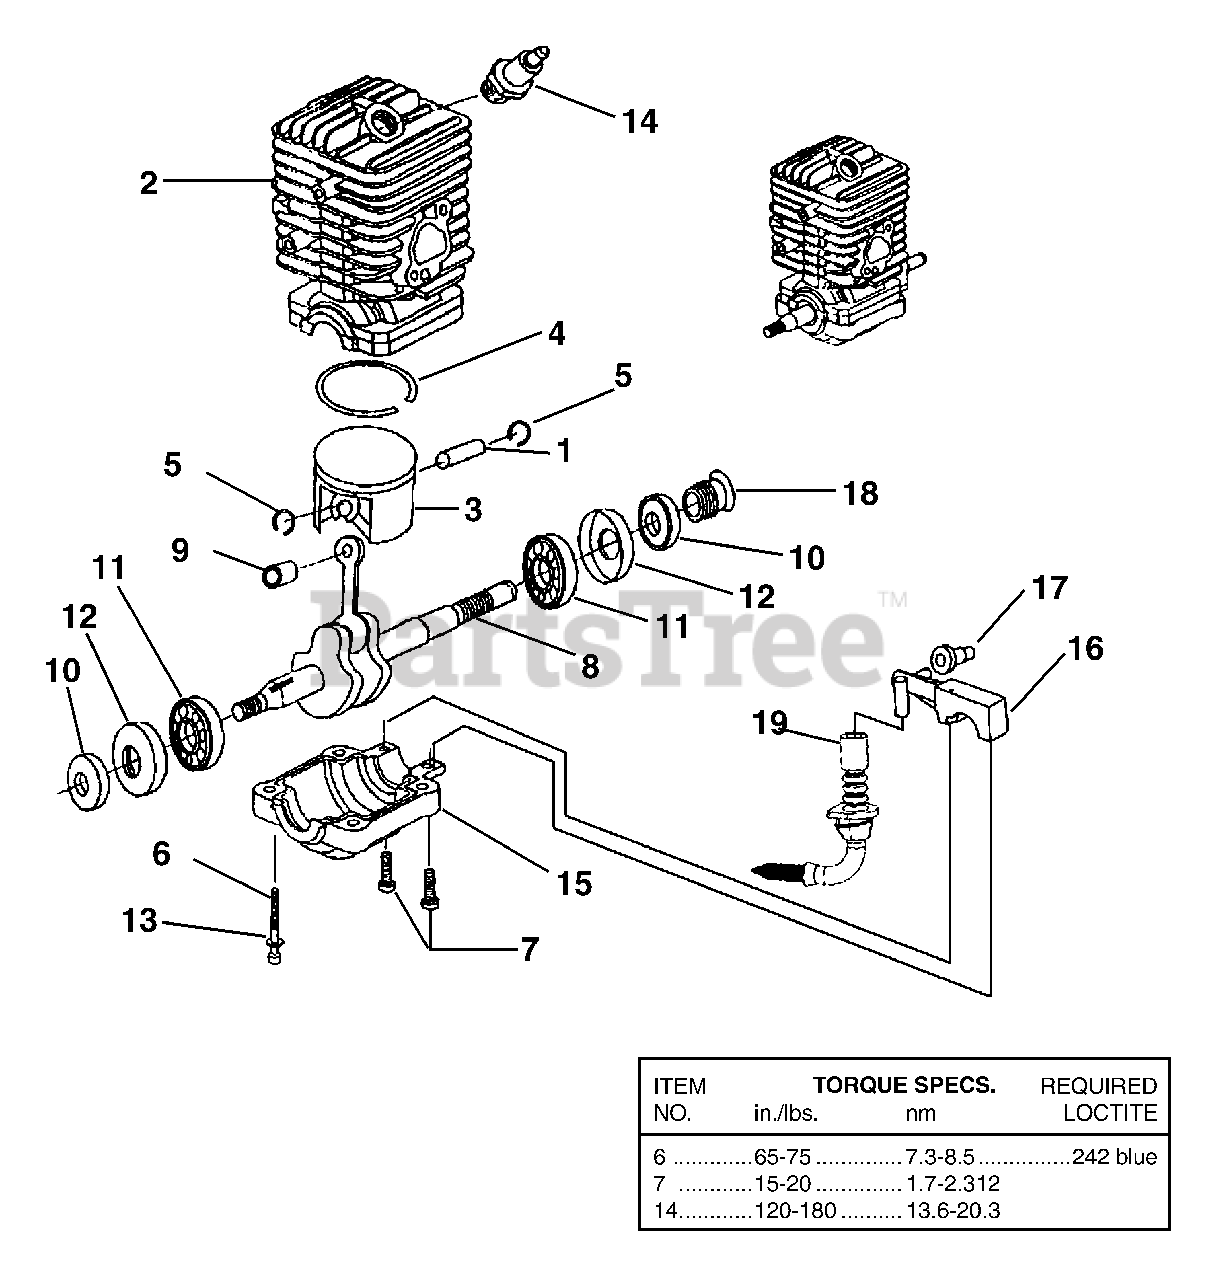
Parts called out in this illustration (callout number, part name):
1	PISTON RING
2	CYLINDER MACH/PLATED
3	45CC PISTON (MACH)
4	PISTON RING
5	RETAINING RING
6	SCREW TORX PLUS CAP-SOCKET HD
7	SCREW, (8/32 X 5/8 in. PAN HD TORX)
8	45CC SINTERED METAL CRANKSHAFT ASSY.
9	NEEDLE BEARING
10	SHAFT SEAL
11	BALL BEARING
12	BEARING CASE
13	FLAT WASHER
14	SPARK PLUG
15	CRANKCASE (45CC) CS
16	OIL PUMP ASSEMBLY
17	GROMMET, OIL OUTLET
18	LEFT HAND WORM
19	OIL INTAKE TUBE W/FILTER
